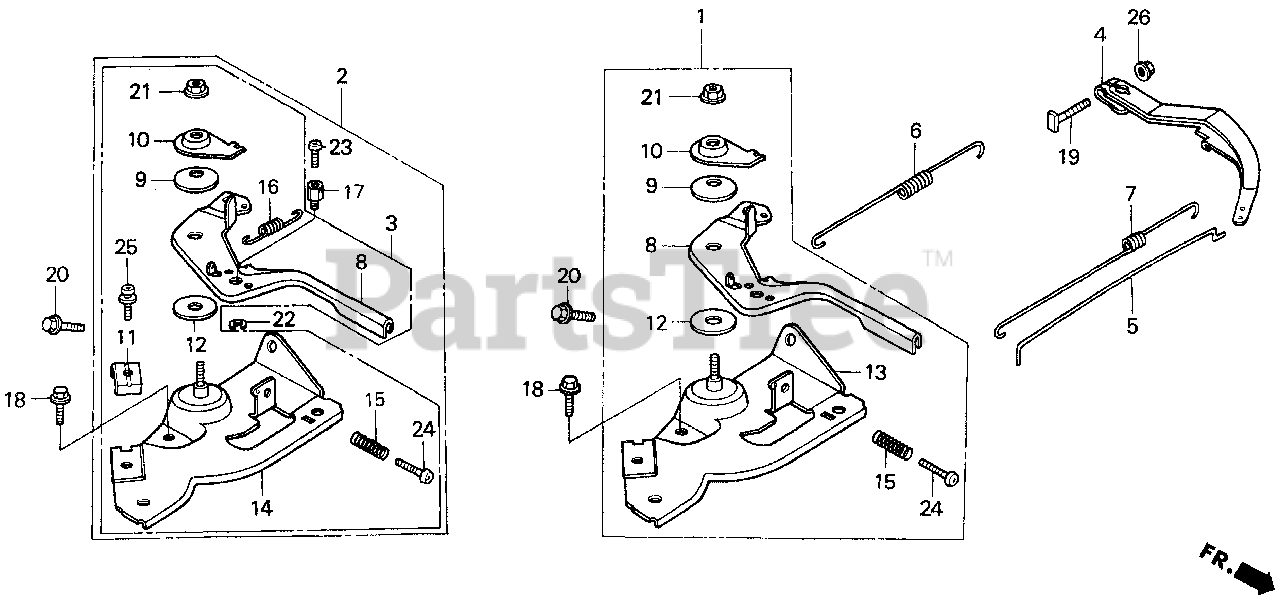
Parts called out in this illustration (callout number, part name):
3	CONTROL ASSY. (REMOTE)
4	ARM, GOVERNOR
5	ROD, GOVERNOR
6	SPRING, GOVERNOR
7	SPRING, THROTTLE RETURN
8	LEVER, CONTROL
9	SPRING, LEVER
10	WASHER, CONTROL LEVER
11	HOLDER, CABLE
12	SPACER, CONTROL LEVER
14	BASE, CONTROL
15	SPRING, CONTROL ADJUSTING
16	SPRING, CABLE RETURN
18	BOLT, FLANGE (6X12) (CT200)
19	BOLT, GOVERNOR ARM
20	BOLT, FLANGE (6X20) (CT200)
21	NUT, SELF-LOCK (6MM)
24	SCREW, PAN (5X25)
25	SCREW, PAN (5X16)
25	SCREW-WASHER (5X16)
26	NUT, FLANGE (6MM)
